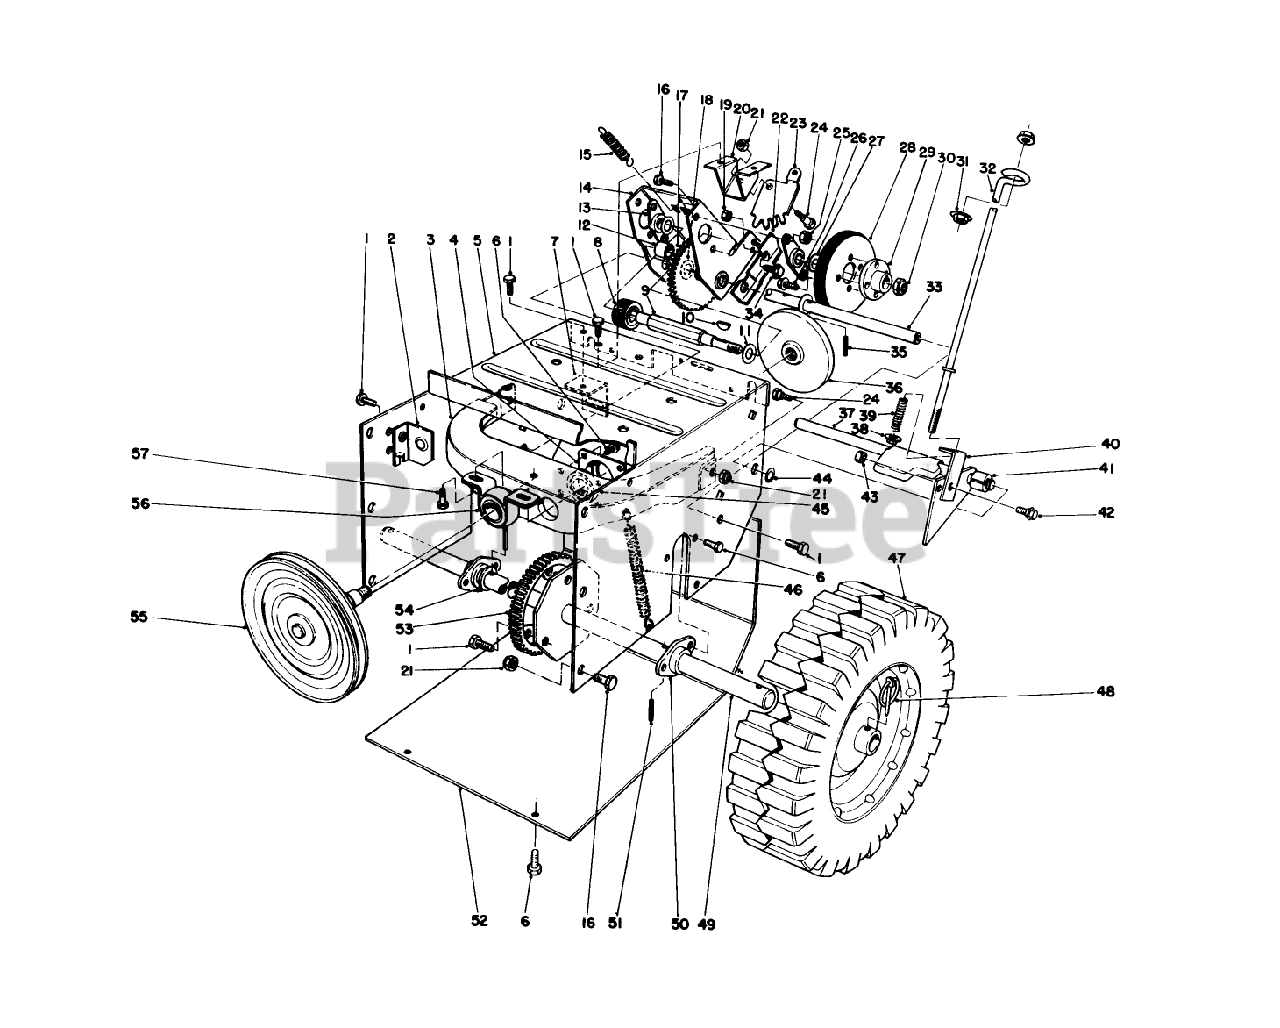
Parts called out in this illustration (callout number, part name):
1	SCREW-HWHTF
3	FRICTION PLT FRAME
4	CUP-BEARING
6	SCREW-HWH
7	BRACKET-MOUNT, REAR
8	PINION
9	SHAFT-WHEEL, FRICTION
10	KEY-WOODRUFF
11	WASHER-FLAT
12	5/8ID X 1LG BUSHING
13	BEARING-WHEEL, FRICTION
14	BRACKET-SLIDING
15	SPRING-TRACTION
16	SCREW-HH
17	INTERNAL GEAR AND BUSHING ASM
18	WASHER-SPECIAL
19	NUT-LOCK, NI
20	MOUNT-LEVER
21	NUT-LOCK, NI
22	CAM-RECEIVER
23	GEAR-QUADRANT
24	BOLT-SHOULDER
25	NUT-LOCK, CONE
26	SCREW-HWHTF
27	WASHER-THRUST
28	WHEEL-FRICTION
29	HUB-WHEEL, FRICTION
30	NUT-LOCK, NI
31	NUT-HF
32	ROD-TRACTION, LOWER
33	SHAFT-PIVOT
35	PIN-SPRING
36	PLATE-FRICTION
38	NUT-HHF
39	SPRING
40	BRACKET-TRACTION
41	SPACER
42	SCREW
43	NUT-LOCK, NI
44	RING-RETAINING
45	BEARING-BALL
46	SPRING-PLATE, FRICTION
48	PIN-LYNCH
49	AXLE SHAFT WA
50	BEARING-AXLE
51	PIN-SPRING
53	GEAR-AXLE
54	WASHER-THRUST
57	SCREW-THD ROLL, HWH
